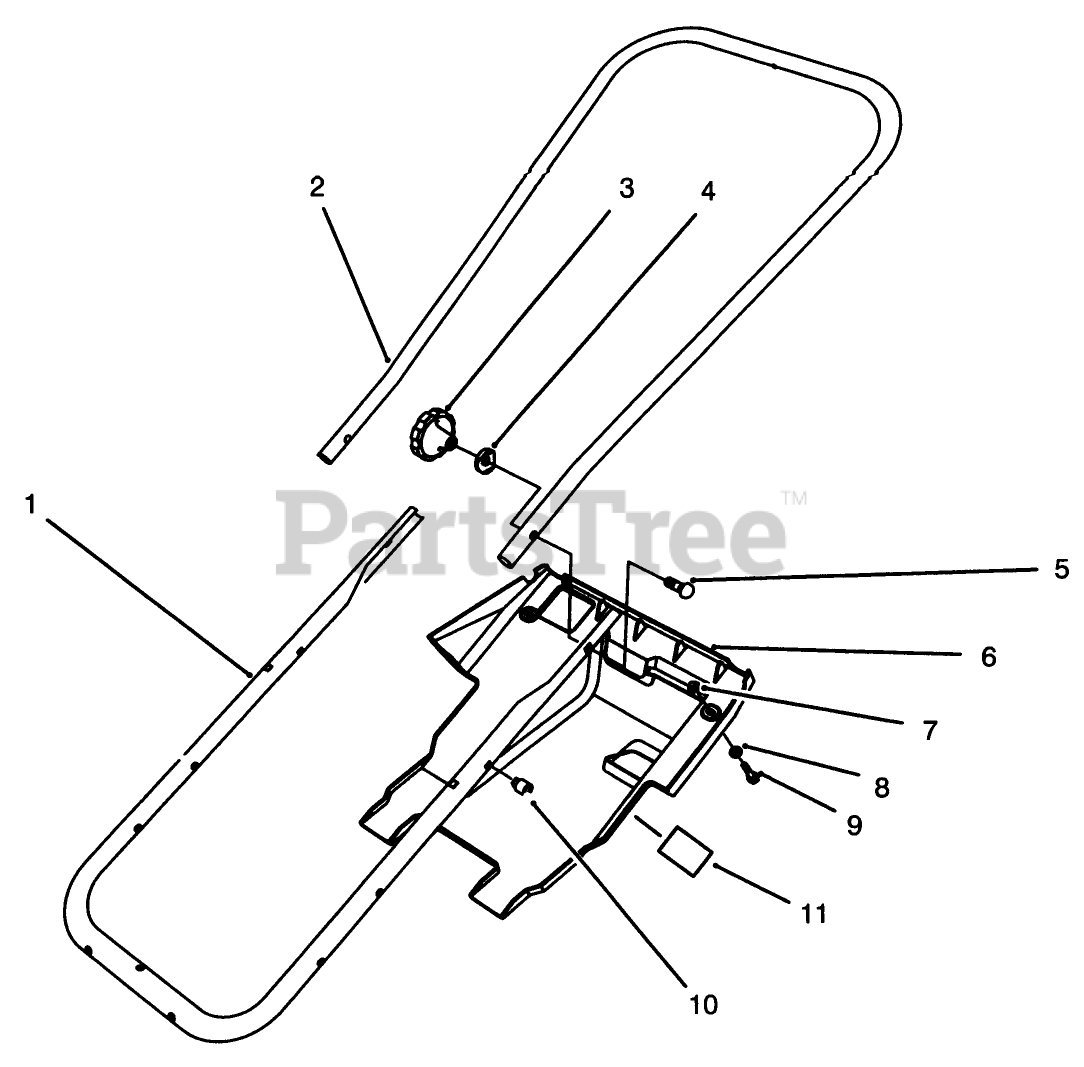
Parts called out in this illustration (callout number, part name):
5	SCREW-HANDLE
6	SHROUD
8	WASHER-FLAT
9	SCREW-HWHTF
10	NUT-EXPANSION
11	DECAL - WARNING
